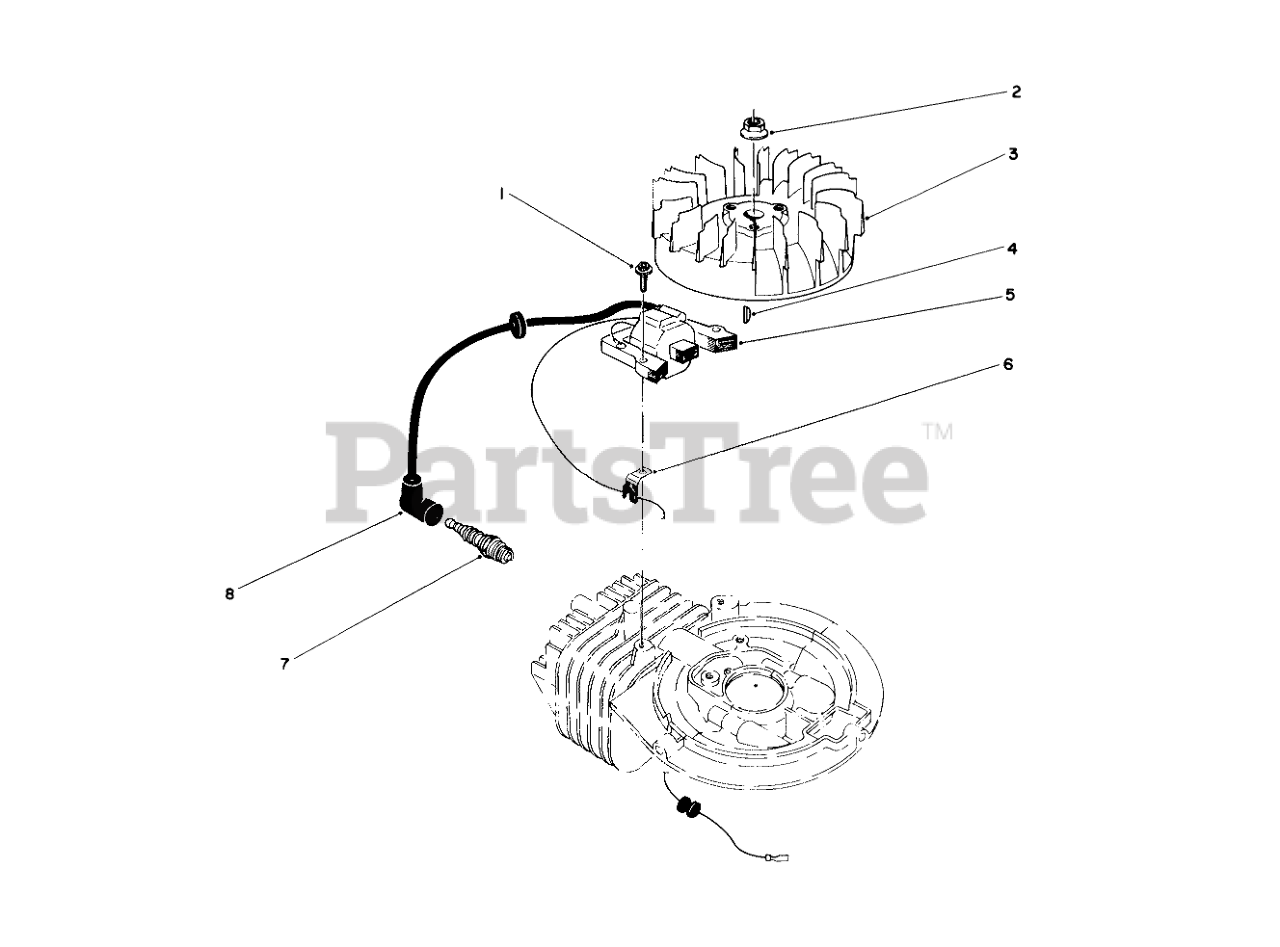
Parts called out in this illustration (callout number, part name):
1	SCREW
3	FLYWHEEL
5	COIL-MAGNETO
6	CLAMP
7	Sparkplug
8	CAP-SPARKPLUG
